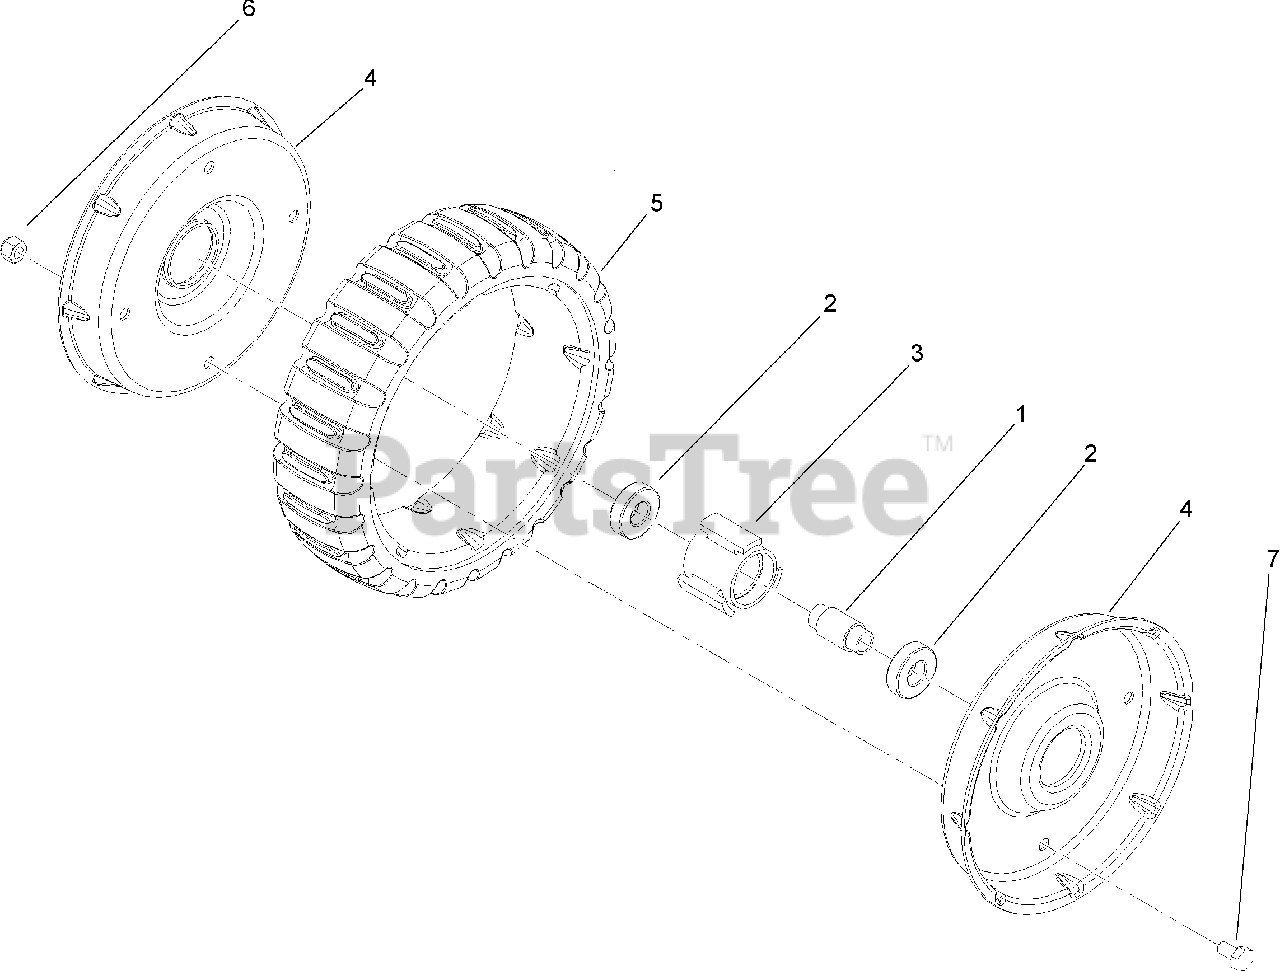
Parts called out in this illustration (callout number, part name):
1	SPACER-BEARING
2	BEARING-WHEEL
3	HUB-BEARING
4	WHEEL HALF
5	TIRE-8 INCH
6	NUT-LOCK, NI
7	SCREW-HH
